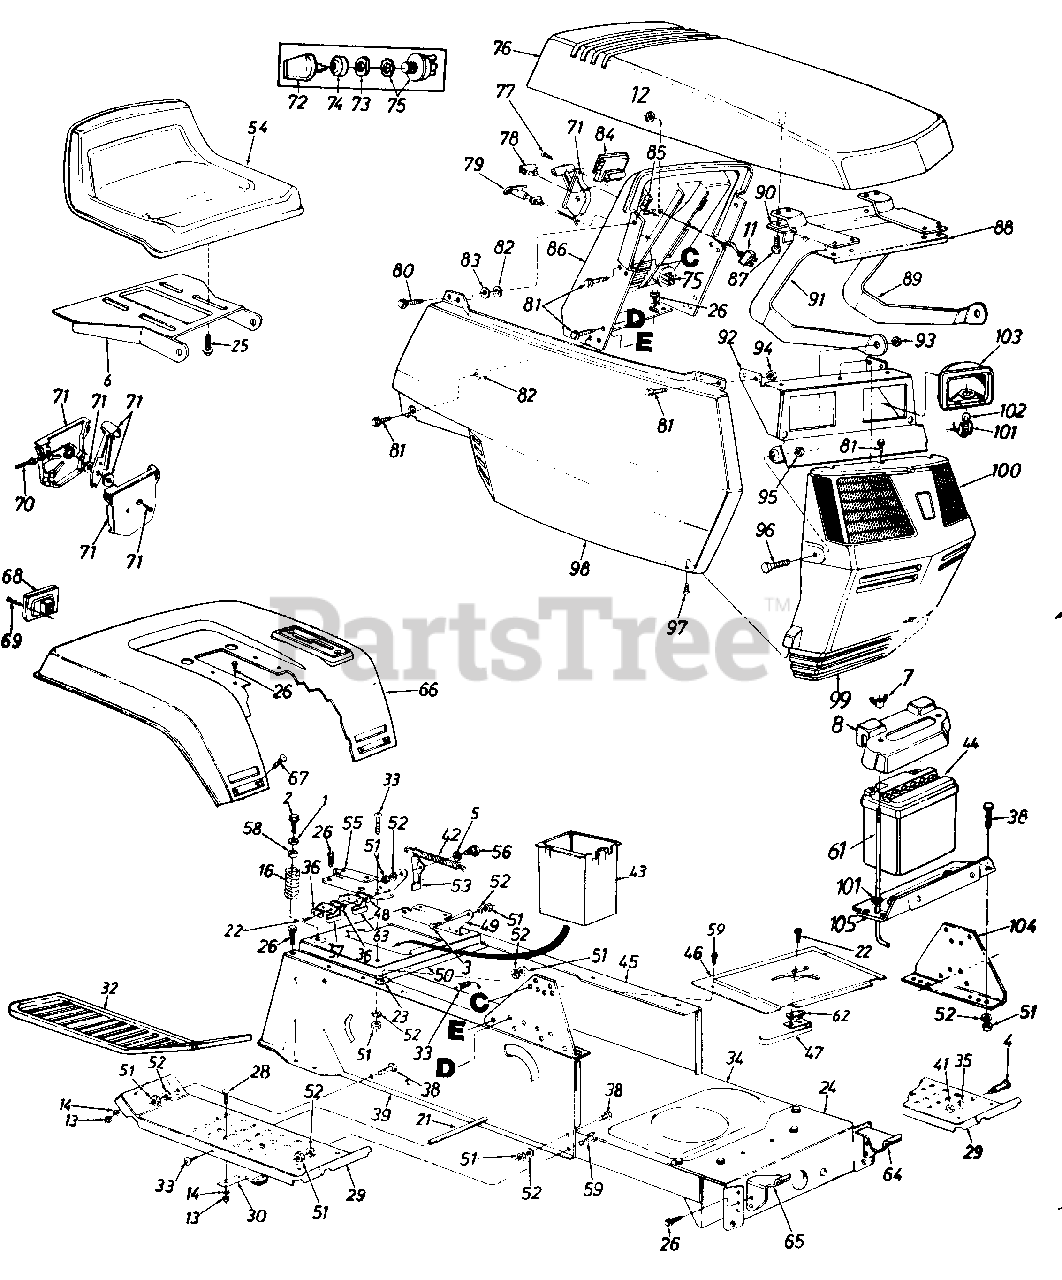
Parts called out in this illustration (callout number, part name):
1	Fl-Wash. .344" I.D. x .875"
2	Hex Wash. Hd. Tap Scr. 5/16-18 x 1.25" Lg.
3	Shld. Bolt .437" Dia. x .162"
4	Shld. Bolt .50" Dia. x .84"
5	Spr-Wash. .445" I.D. x .7.5
6	Seat Pivot Bracket
7	Wing Nut 1/4-20 Thd.
8	Battery Cover
11	Toggle Switch
12	Hex Nut 1/2-27 Thd.
13	Hex Nut 1/4-20 Thd.
14	L-Wash. 1/4" I.D.
16	Compression Spring
21	Running Board Rod
22	Hex Wash. Hd. AB-Tap Scr. #8 x .50" Lg.
23	Speed Nut #10Z
24	Front Pivot Brkt.
25	Hex Tap Scr. 3/8-16 x .75"
26	Hex Wash. Hd. AB-Tap Scr. 5/16 x .75" Lg.
28	Carriage Bolt 1/4-20 x .62"
29	Running Board
30	Blade Brake Ass'y.
32	Rubber Foot Pad L.H.
33	Truss Mach. Scr. 5/16-18 x .75" Lg.
34	Lower Frame
35	L-Wash. 3/8" I.D.
36	Insulator Plate
38	Hex Bolt 5/16-18 x .75" Lg.
39	Upper Frame R.H.
41	Hex Nut 3/8-16 Thd.
42	Extension Spring 5.31" Lg.
43	Utility Box
44	12-V Battery (275 Cold Crank Amps)
45	Upper Frame L.H.
46	Shift Cover
47	Reverse Safety Switch
48	Insulator Boss Plate
51	Hex Nut 5/16-18 Thd.
52	L-Wash. 5/16" I.D.
53	Seat Lift Brkt.
54	Seat
57	Spring Switch
58	Bushing
59	Truss Hd. Scr. 5/16-18 x 1.0" Lg.
61	Battery Hold Down Rod
62	Insulator Nut Plate
63	Safety Switch (Seat)
64	Grille Mount Brkt. L.H.
65	Grille Mount Brkt. R.H.
68	Taillight
69	Truss Hd. AB-Tap Scr. #6 x .62" Lg.
70	Throttle Wire 35" Lg.
71	Throttle Control Box Ass'y.
72	Ignition Key
73	Ignition Switch Nut
74	Ignition Switch Cap
75	Ignition Switch
78	Light Switch
79	Choke Control 38" Lg.
80	Hex Wash. Hd. Tap Scr. 1/4 x .75" Lg.
81	Hex Tap Scr. 1/4-20 x .5" Lg.
82	Push Nut Fastener
83	Fl-Wash. .27" I.D. x .948"
84	Ammeter
85	Speed Nut 1/4-20 Thd.
86	Dash Panel
87	Hex Wash. Hd. B-Tap Scr. 1/4 x .62" Lg.
88	Hood Reinforcement
89	Hood Hinge L.H.
94	Hex L-Nut 1/4-20 Thd.
95	Hex Jam Nut 5/16-18 Thd.
96	Hex Bolt 5/16-18 x 7/8" Lg.
97	Truss Mach. B-Tap Scr. #10 x .5" Lg.
98	Side Cover R.H.
99	Grille
100	Lens L.H.
101	Twist Lock Lamp Socket
102	Lamp
103	Headlight Housing
104	Dash Support Brkt.
105	Support Brkt.
